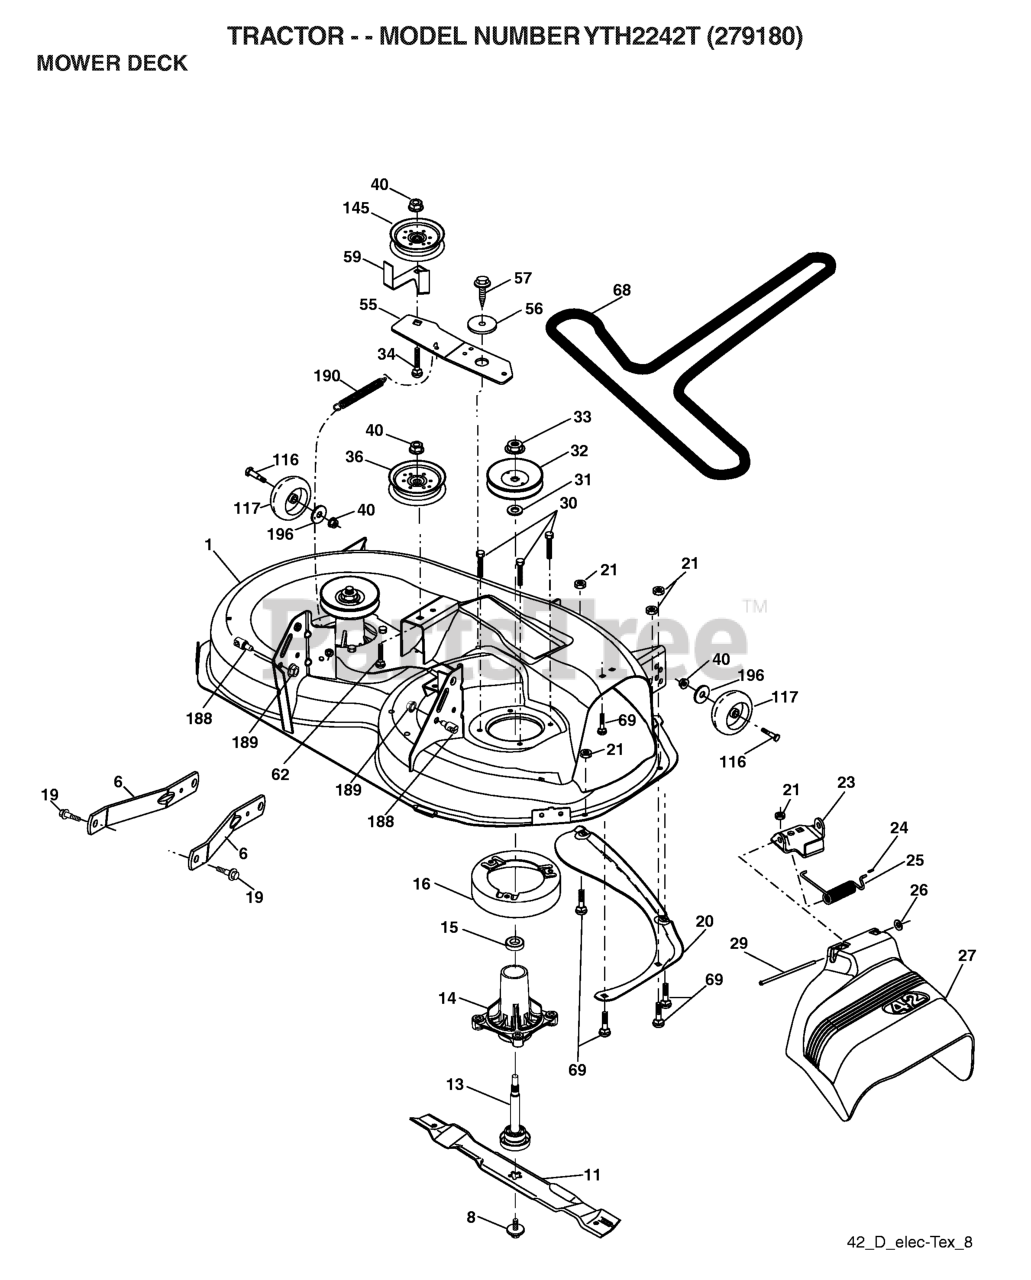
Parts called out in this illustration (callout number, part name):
1	DECK.WELDMENT.42"PAINT
6	ARM.SUSPENSION.MOWER.R
8	BOLT.WASHER.ASM.7/16-2
11	42" HI-LIFT BLADE
13	SHAFT.ASM.MDRL.N/GREASE.38
14	RP.HOUSING.MANDREL.4PT.
16	STRIPPER.MANDREL.ROUND.BLACK
19	BOLT.SHOULDER
20	BAFFLE.VORTEX
21	LOCKNUT
23	BRKT.DEFLECTOR.38"2005+
24	CAP-SLEEVE LT
25	SPRING.TORSION.DEFLECT
26	NUT PUSH M
27	SHIELD.DEFLECTOR.MOWER.42"BLAC
29	ROD.HINGE
30	SCREW, WASHER HEAD
31	WASHER.SPACER.MANDREL
32	PULLEY MANDREL
33	NUT.FLANGE.LOCK.TOP
34	BOLT.3/8-16X1.50
36	PULLEY.IDLER.2006
40	NUT LOCK FLG 3/8-16 UNC
56	SPACER.RETAINER
57	SCREW 3/8-16X1
59	GUARD, BELT
68	BELT V SECONDARY
69	BOLT
116	BOLT.SHOULDER.3/8-16X3-5/8.
117	RP WHEEL. GUAGE RALLY
145	PULLEY.IDLER.FLAT
188	STUD.FASTNER.W/ANTI-ROTATE
189	NUT LOCK HEX FLANGE 5/16-18
190	SPRING.MOWER.DRIVE.ELECTRIC
196	WASHER
